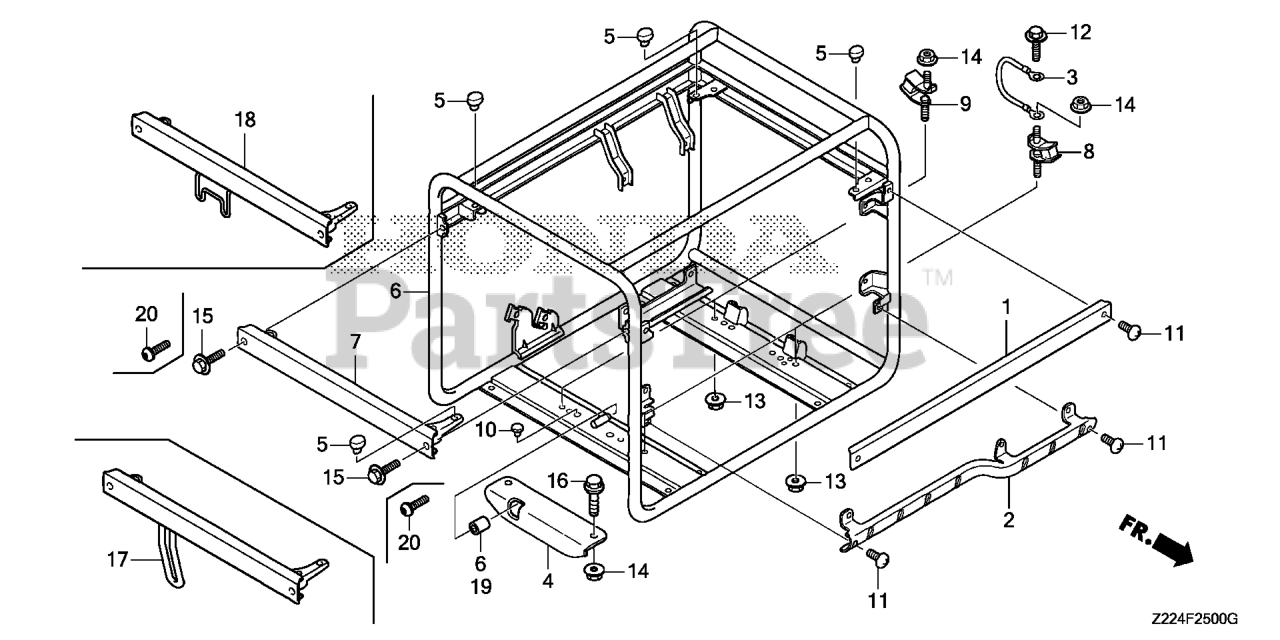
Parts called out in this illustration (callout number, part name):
1	GUARD, CONTROL PANEL (UPPER) *NH105* (MAT BLACK)
2	GUARD, CONTROL PANEL (LOWER) *NH105* (MAT BLACK)
3	CABLE, SUB-GROUND
4	BRACKET, STOPPER
5	RUBBER, FUEL TANK MOUNTING
6	FRAME *NH105* (MAT BLACK)
7	FRAME, SIDE *NH105* (MAT BLACK)
8	RUBBER (LOWER)
9	RUBBER (LOWER)
10	RUBBER, BUMP STOP
11	SCREW, TRUSS (6X12)
12	BOLT, GROUND (6X16) (WASHER 12.5MM) (ZN)
13	NUT, FLANGE (8MM)
14	NUT, FLANGE (10MM)
15	BOLT, FLANGE (8X16)
16	BOLT, FLANGE (10X40)
